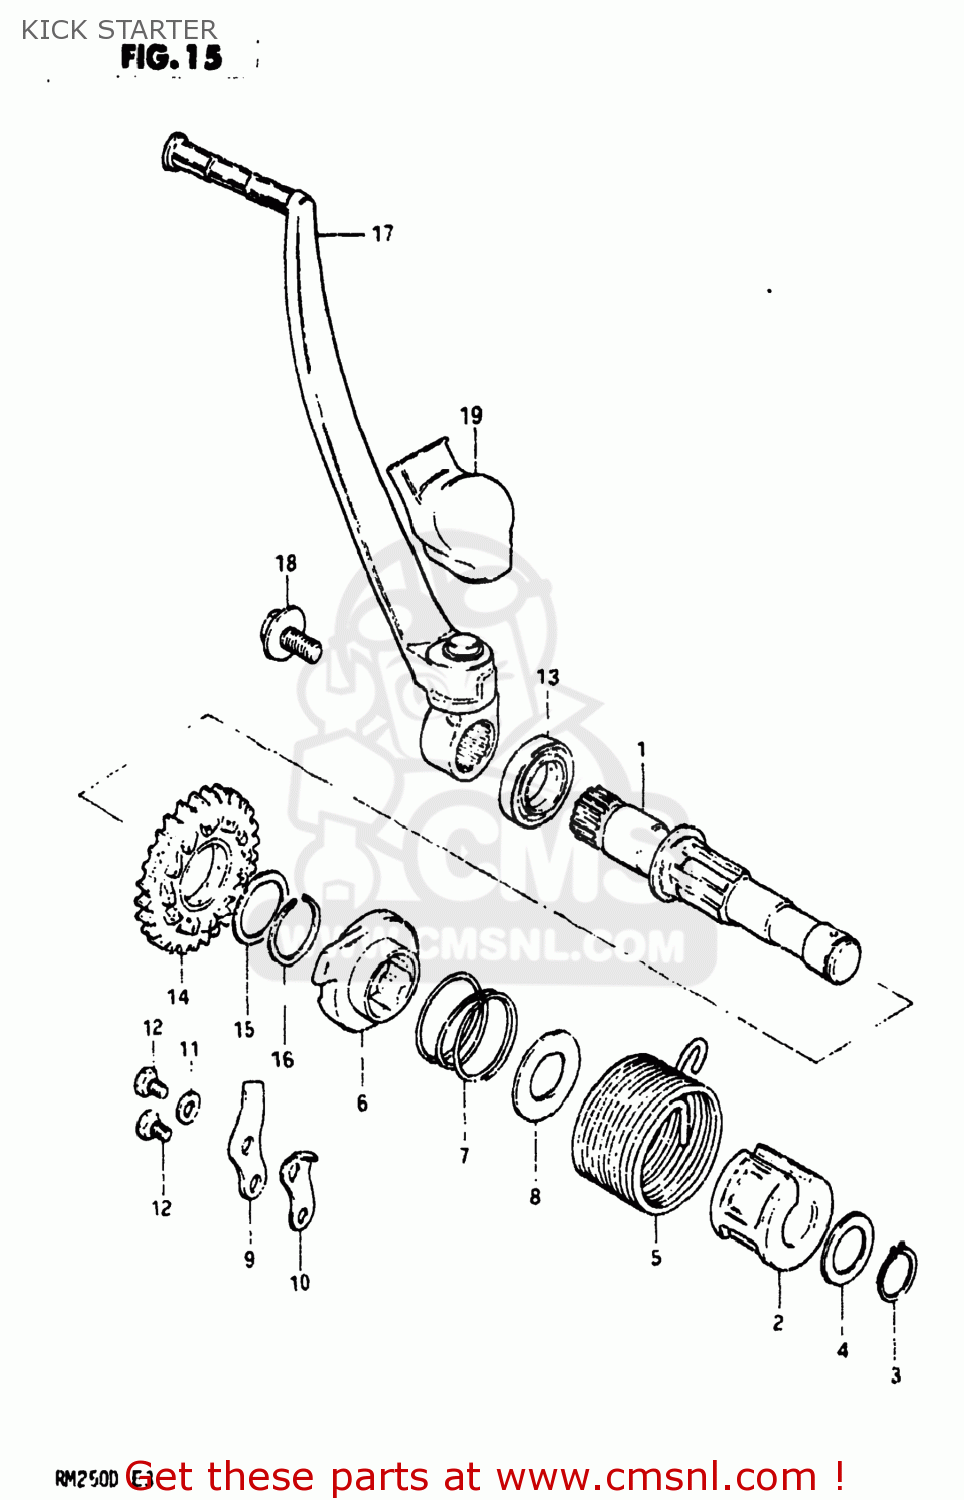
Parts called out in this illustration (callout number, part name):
1	SHAFT,KICK STARTER
2	GUIDE,KICK STARTER SFT SPRING
3	CIRCLIP
4	WASHER
5	SPRING
6	STARTER,KICK
7	SPRING
8	WASHER
9	GUIDE,KICK STARTER
10	STOPPER,KICK STARTER
11	WASHER
12	BOLT
13	SEAL,OIL(20X27X5)
14	GEAR,KICK STARTER DRIVE
15	SHIM
16	CIRCLIP
17	LEVER ASSEMBLY,KICK STARTER
18	BOLT(8X14)
19	COVER,KICK STARTER LEVER JOINT
